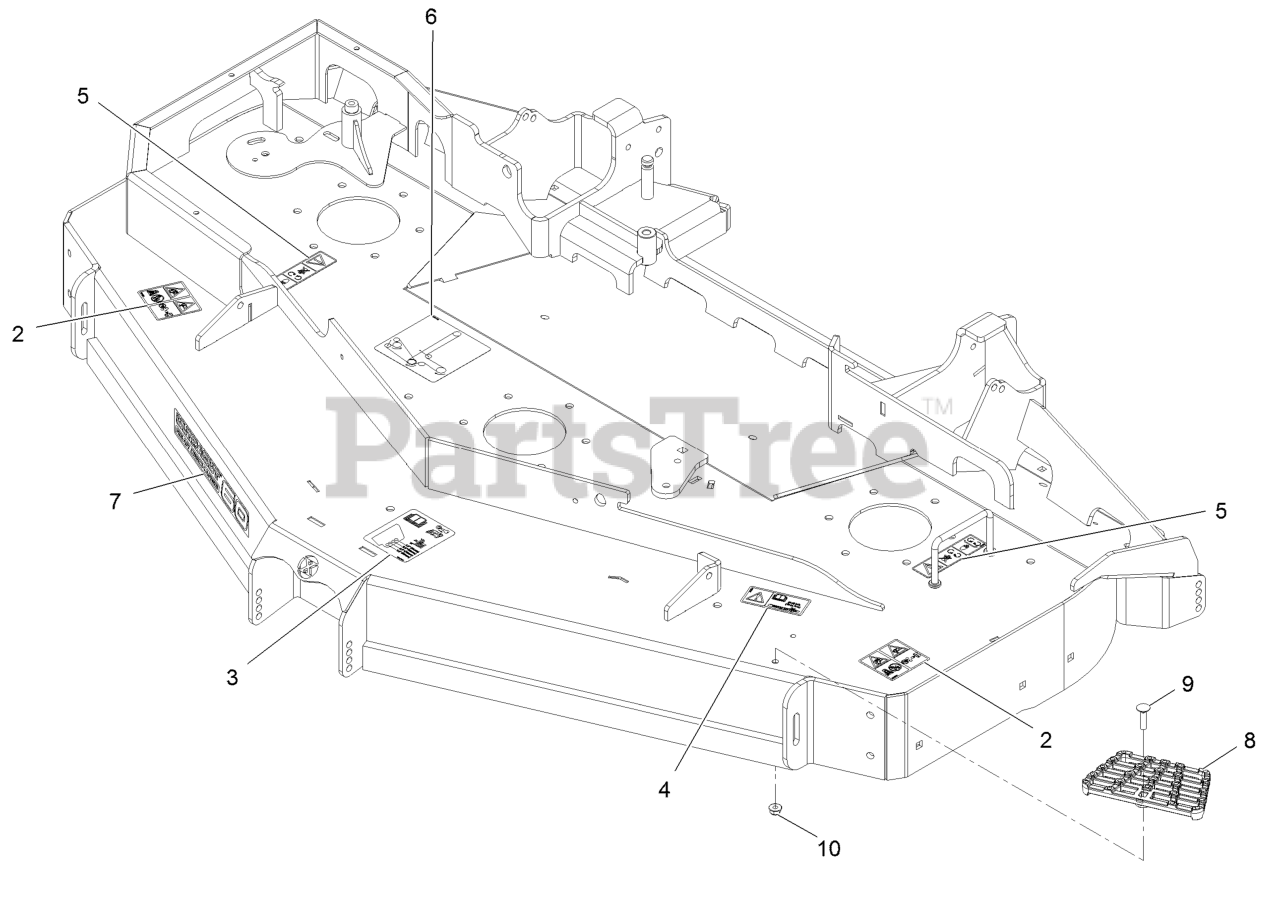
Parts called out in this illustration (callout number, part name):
2	Decal-Danger
3	Decal-Roller, Anti-Scalp
4	Decal-Bolt Torque
5	Decal-Missing, Cover
6	Decal-Routing, Belt
7	Decal, 60Rd
8	Step-Deck
9	Bolt-Carriage 5/16-18 X 1 1/4
10	Nut-Nyloc 5/16-18 Flg
